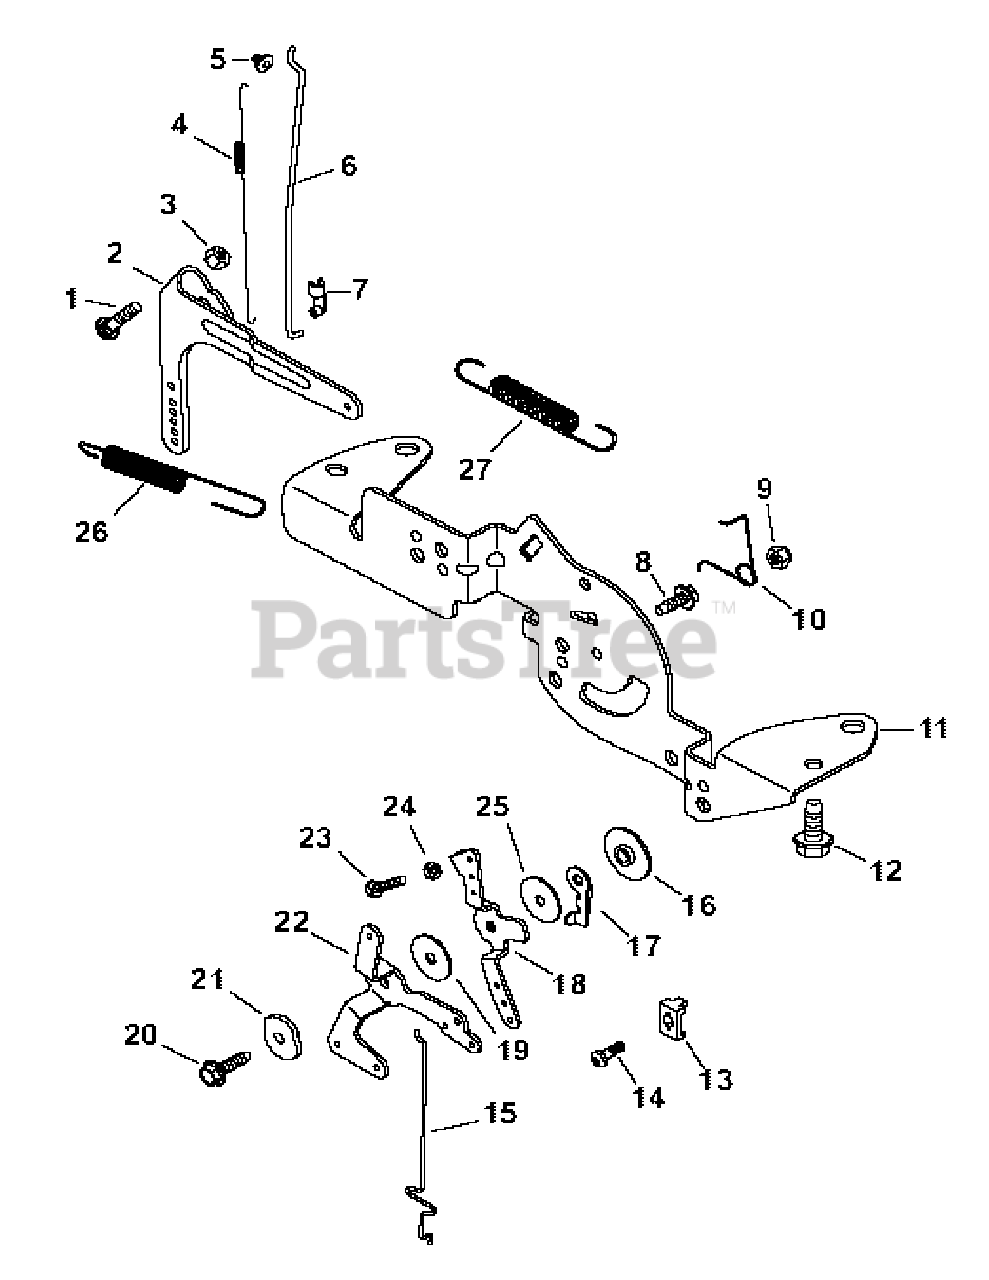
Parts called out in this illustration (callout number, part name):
1	Round Head Square Neck Bolt
2	Governor Lever
3	Hex Flange Nut
4	Linkage Spring
5	Linkage Retaining Bushing
6	Throttle Linkage
7	BUSHING-RETAINING
8	Hex Flange Screw
10	Choke Return Spring
11	Control Bracket
12	Hex Flange Screw
13	Dual Conduit Clamp
14	Thread Forming Screw
15	Choke Linkage
16	Control Assembly Spacer
17	Throttle Actuator Lever
18	Throttle Control Lever
19	Plain Washer 5.5mm
20	Hex Flange Screw
21	Spring Washer 1/4"
23	Hex Head Cap Screw
26	Governor Spring
27	Governor Spring
